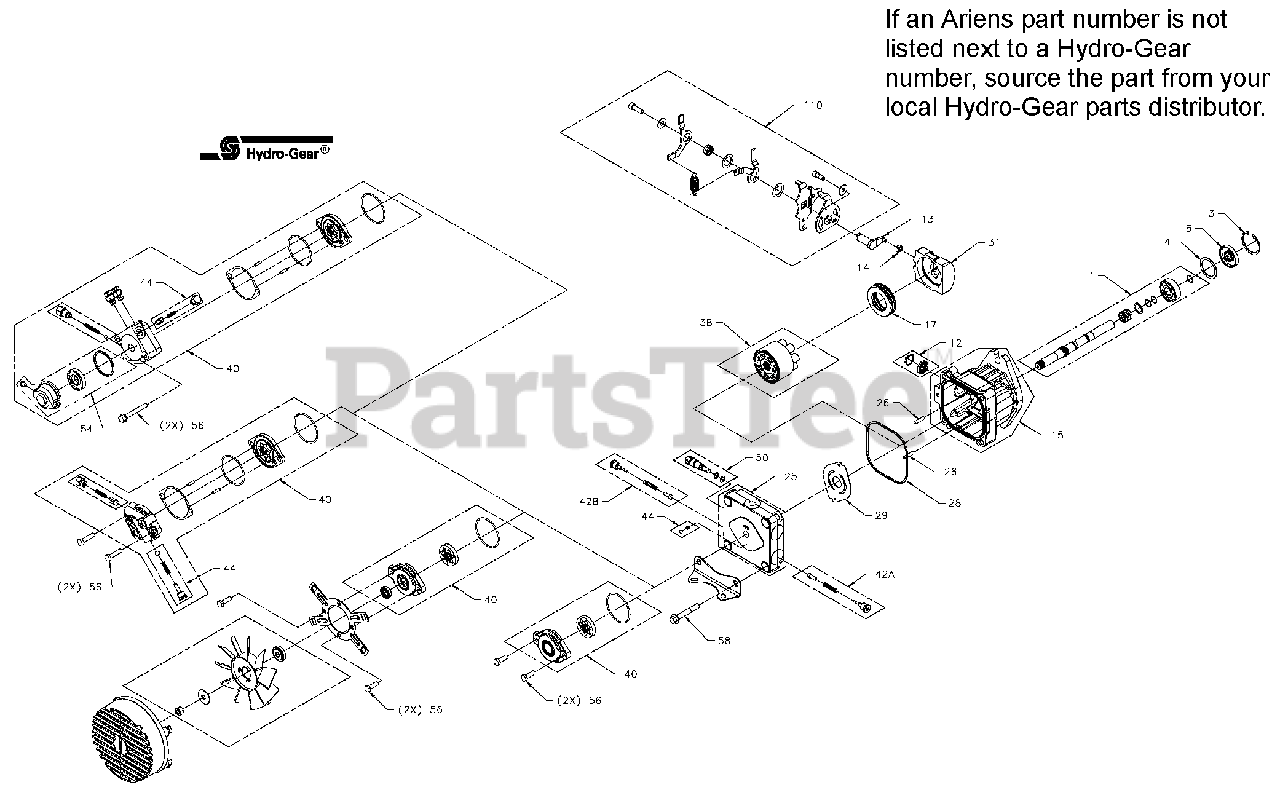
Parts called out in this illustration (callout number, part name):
1	KIT, PUMP SHAFT
3	RING, RET 47 INT
4	WASHER, 1.45X1.84X.04
6	SEAL, LIP 17X47X8
12	KIT, BDP-16A TRUNNION SEA
13	ARM, TRUNNION
14	GUIDE. SLOT
15	SERVICE KIT, HOUSING
17	BRG, THRUST BALL 42X68X16
25	KIT, END CAP
26	PIN, .219X1
28	O-RING, SQ .1X(4.3X4.6)
29	VALVE PLATE
31	PLATE, SWASH 21CC
38	KIT, MOTOR BLOCK
40	Kit, Charge Pump
42	KIT, SHOCK VALVE 200 BAR
44	Kit, Charge Relief
50	KIT, BYPASS VALVE
54	KIT, AUX FILTER
56	HFHCS 5/16-18X2.5
58	KIT, BOLT
110	KIT, RTN
